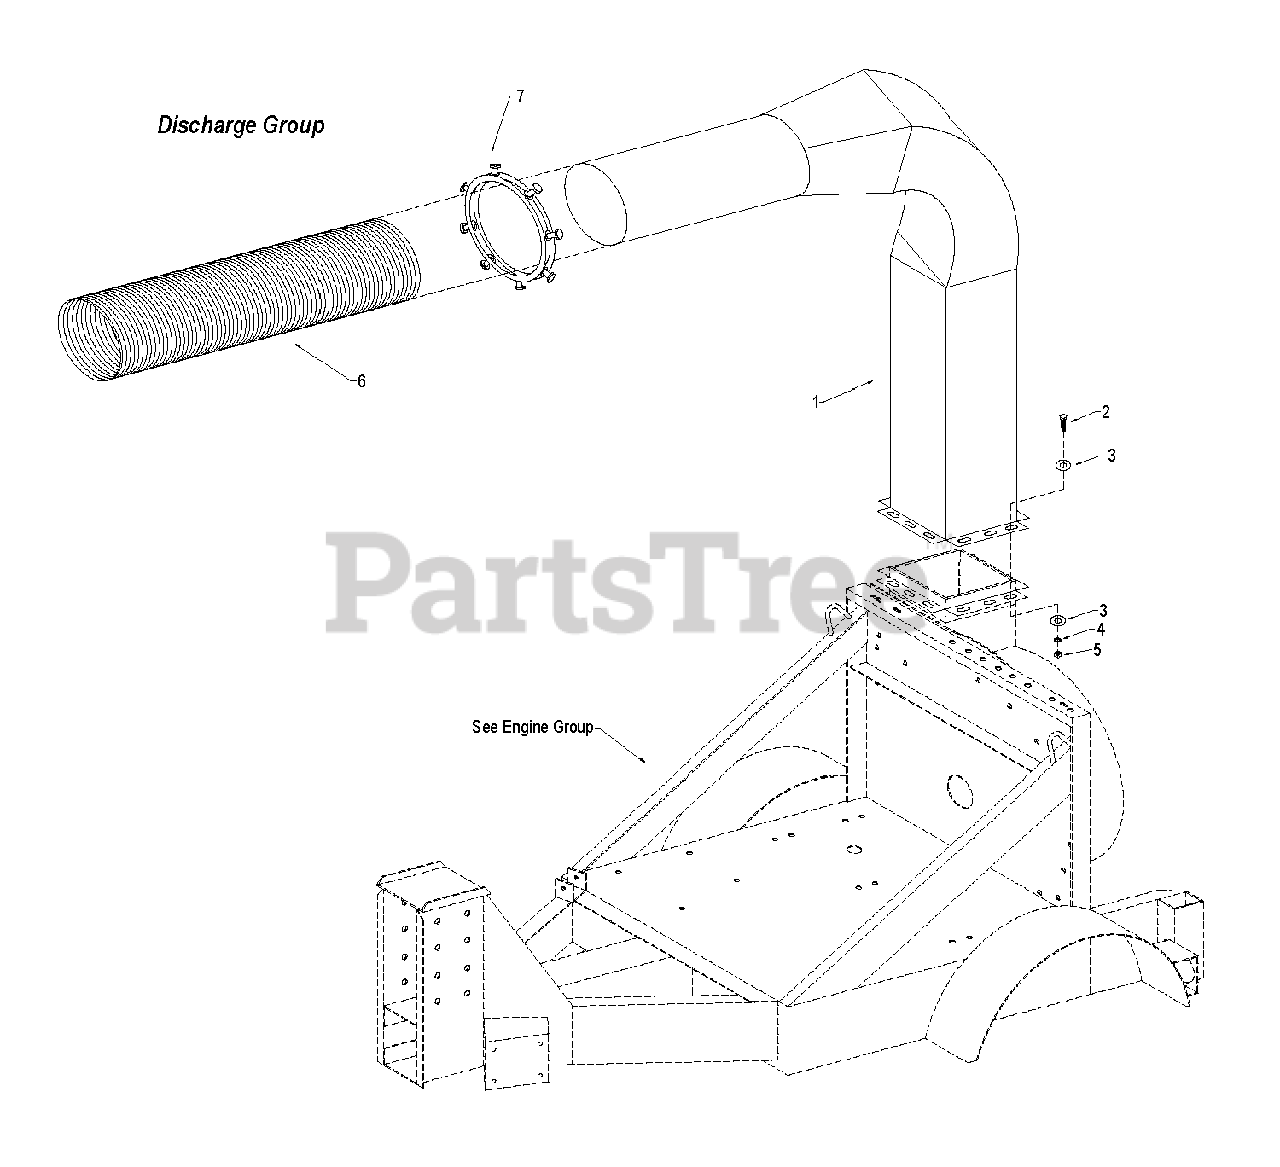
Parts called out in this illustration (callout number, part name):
1	Stack and elbow assy
2	Bolt, hex - 1/2-13 x 1-3/4"
3	Washer, flat - 1/2
4	Washer, lock - 1/2"
5	Nut, hex - 1/2-13
6	Hose, discharge - 12" x 6' metal
7	Ring, squeeze - 12"
